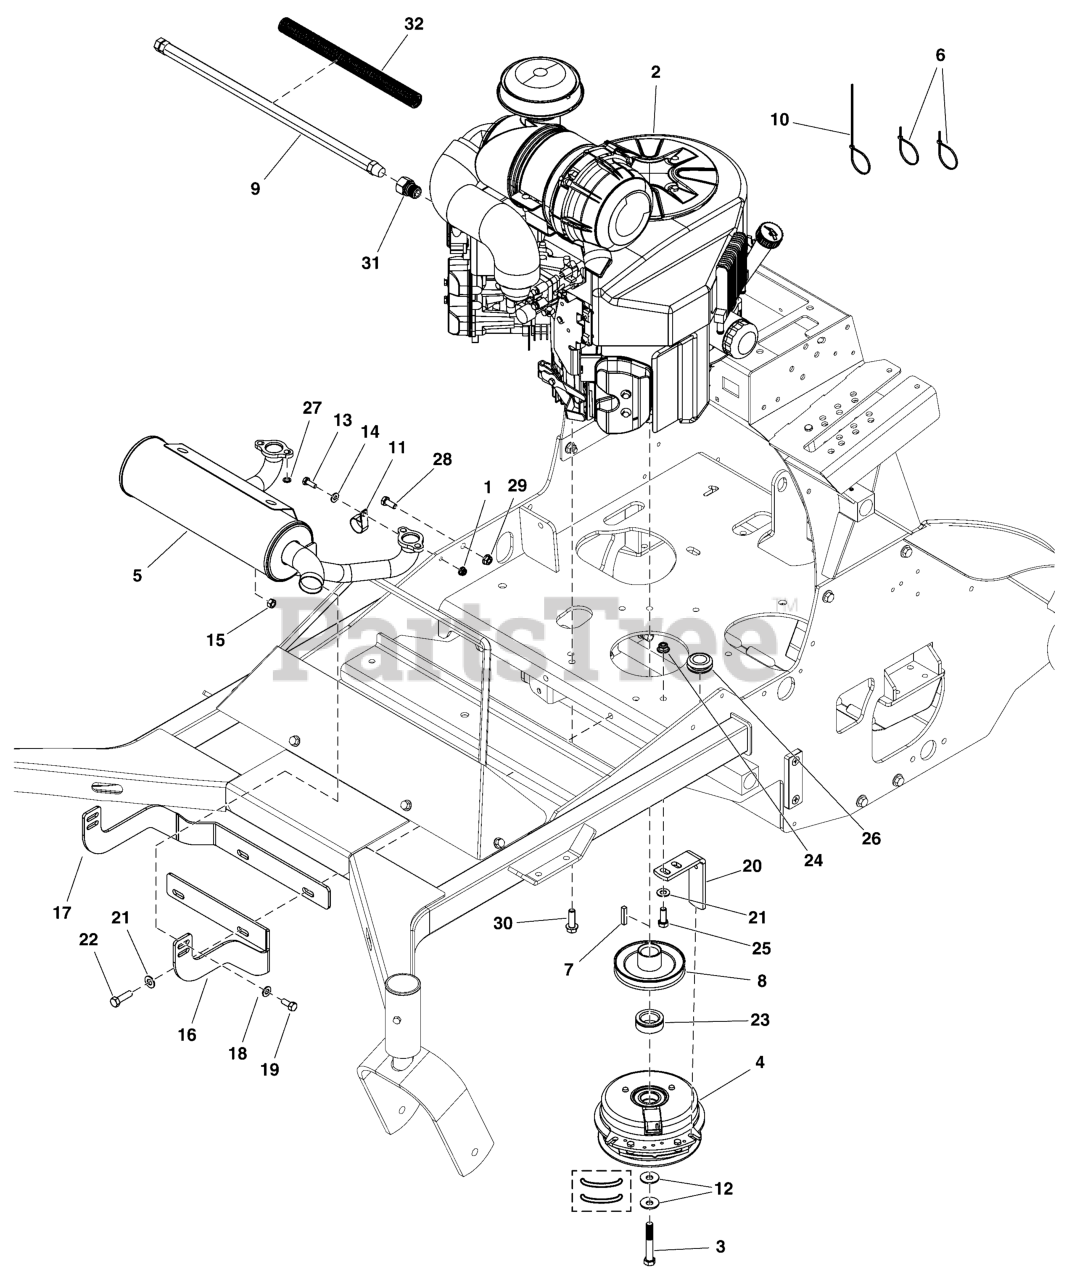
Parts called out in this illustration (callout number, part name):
1	NUT, 1/4-20 Hex Nylock Flange
3	BOLT, CRANKSHAFT, 7/16 X 2-3/4, PATCH, CZ
4	CLUTCH WARNER 200 FT-LB 1.13 X 6.323
5	MUFFLER, 26, KAWASAKI, 801 BLOCK, SRS Z2
6	TIE, SELF-LOCKING, 6"
7	KEY, 1/4" SQ. X 1-1/4
8	PULLEY, CRANKSHAFT, 1.1255 ID X 4.50 OD
9	HOSE, OIL DRAIN
10	TIE,SELF-LOCKING, 24"
11	CLAMP, VINYL INSULATED, 1.00
12	BELLEVILLE WASHER, 1.1875 X .442 X .098
13	BOLT, 1/4"-20 X 3/4" GD5 YZ
14	WASHER, 1/4 SAE
15	NUT, 5/16-1/8, HEX, CNTR LK, ZINC PHOS/OIL
16	PLATE, EXHAUST BRACKET LH - BLK
17	PLATE, EXHAUST BRACKET RH - BLK
18	WASHER, 5/16" SAE
19	BOLT, 5/16-18 X 3/4 GD5
20	ANCHOR, CLUTCH - BLK
21	WASHER, 3/8 SAE
22	BOLT, 3/8-16 X 1-1/4" GD5 CZ
23	SPACER, 1.13 X 1.75 X .63
24	NUT, 3/8 - 16 HEX NYLOCK FLANGE
25	BOLT, 3/8-16 X 1" GD5 CZ
26	GROMMET, 7/8"ID, 1/4" THICK STK
27	WASHER, Light Lock, 5/16
28	BOLT, M8-1.25 X 20 MM GD 8.8
29	NUT, M8-1.25 Hex Serrated Flange
30	BOLT, 3/8-16X1-1/4 SF, GD8, PHOS, SER HD
31	ADAPTER, Oil Drain
32	WIRE LOOM, 3/4 ID X 12 IN
